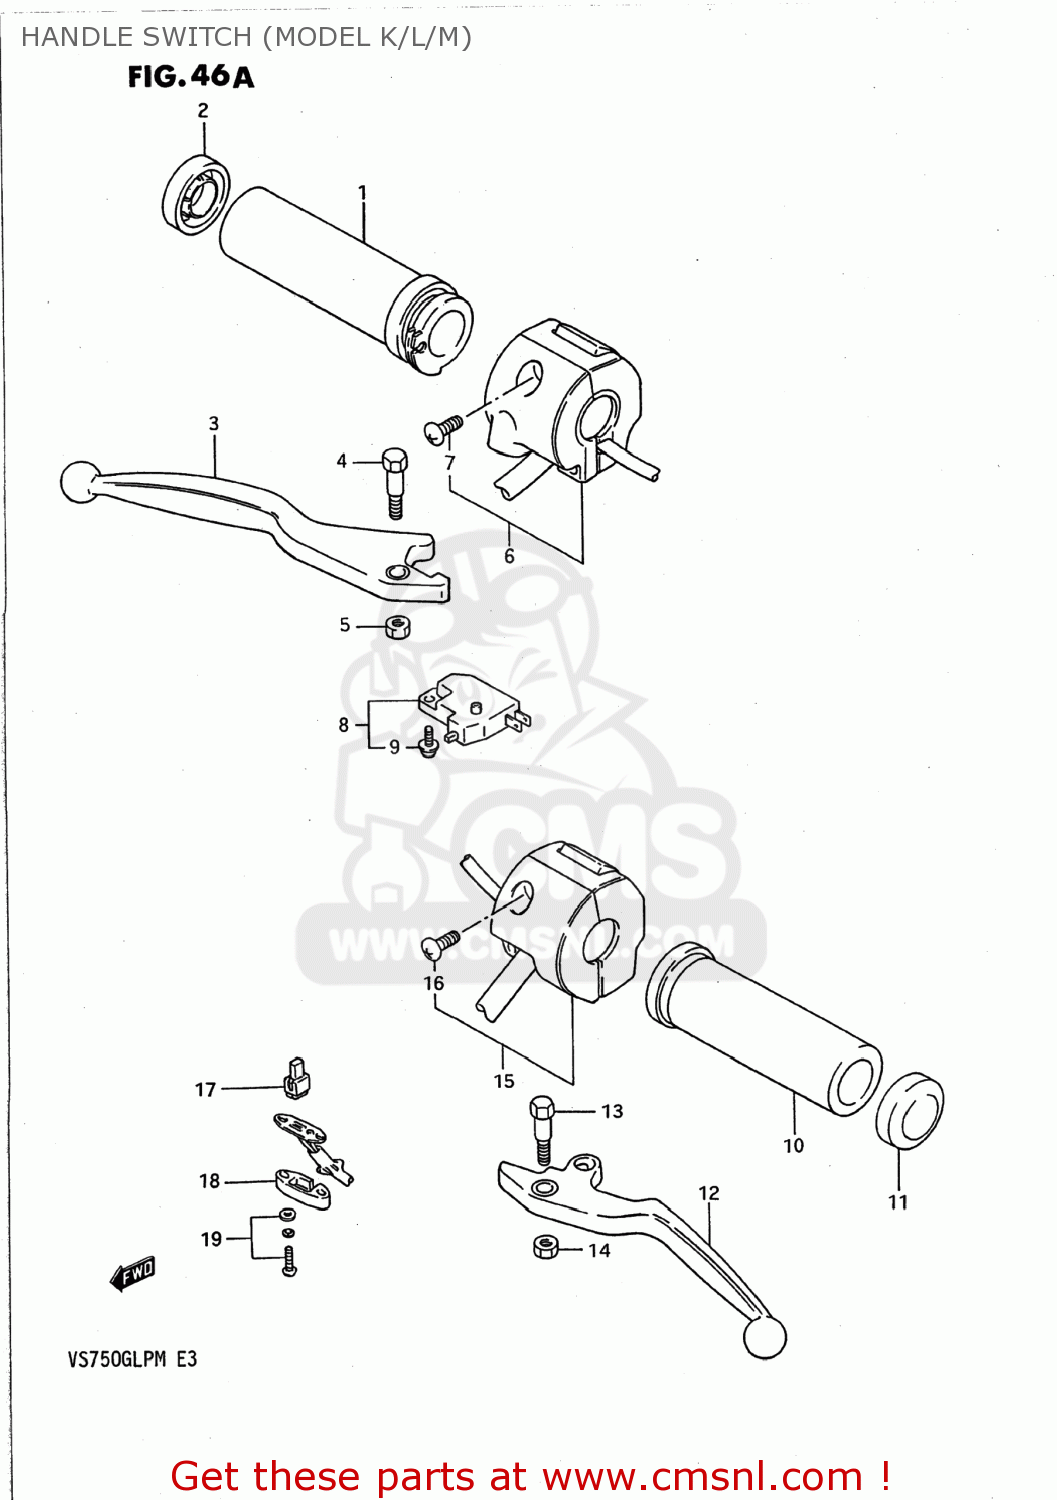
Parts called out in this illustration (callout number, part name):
1	GRIP,THROTTLE
2	CAP,GRIP END
3	LEVER,BRAKE
4	BOLT,LEVER
5	NUT 6MM
6	SWITCH ASSY,HANDLE,R
7	SCREW
8	SWITCH ASSEMBLY,STOP
9	SCREW
10	GRIP,L
11	CAP,GRIP END
12	LEVER,CLUTCH (SILVER)
13	BOLT,LEVER
14	NUT 6MM
15	SWITCH ASSY,HANDLE,L
16	SCREW
17	CONTACT,SWITCH
18	COVER,CLUTCH SWITCH
19	SCREW
